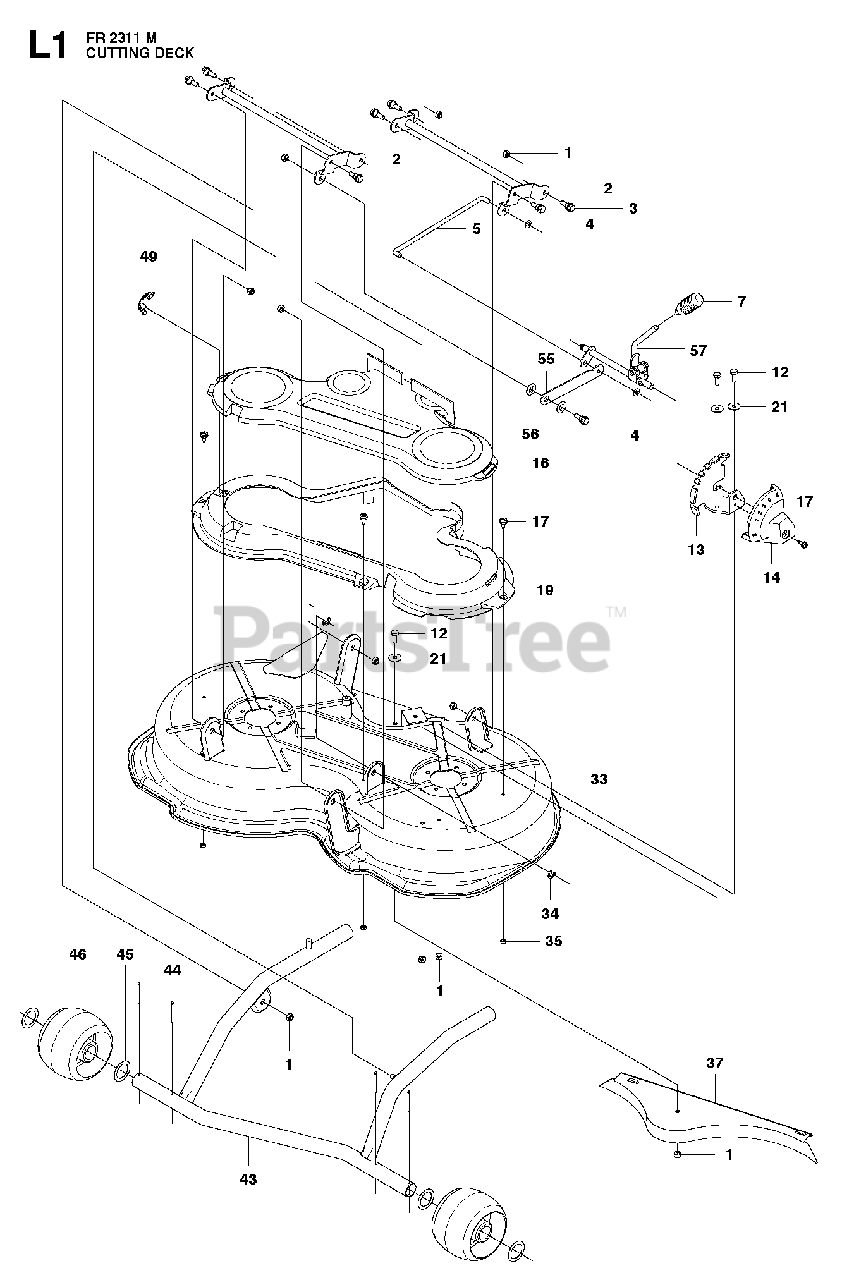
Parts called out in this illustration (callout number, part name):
1	LOCKNUT M8
34	RETAINING RING
35	LOCKNUT M6
44	COTTER PIN
56	WASHER - 25X8.5X2.3
